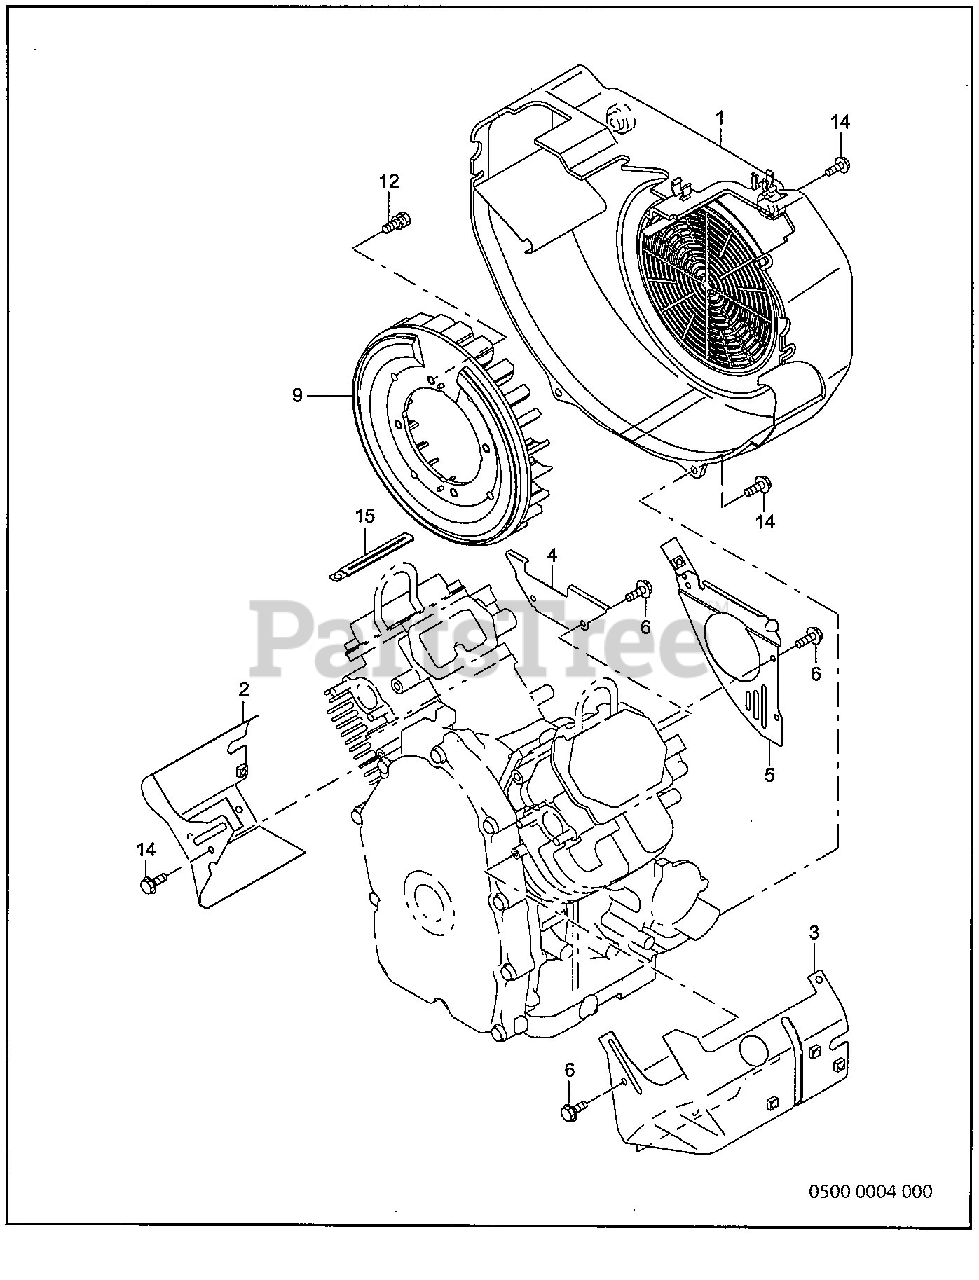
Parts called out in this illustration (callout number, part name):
1	BLOWER HOUSING UNIT
2	CYLINDER BAFFLE 1 ASSY
3	CYLINDER BAFFLE 2 ASSY
4	CYLINDER BAFFLE 3
5	CYLINDER BAFFLE 4 UNIT
6	FLANGE BOLT
9	COOLING BLOWER UNIT
12	BOLT and WASHER ASSY
14	FLANGE BOLT
